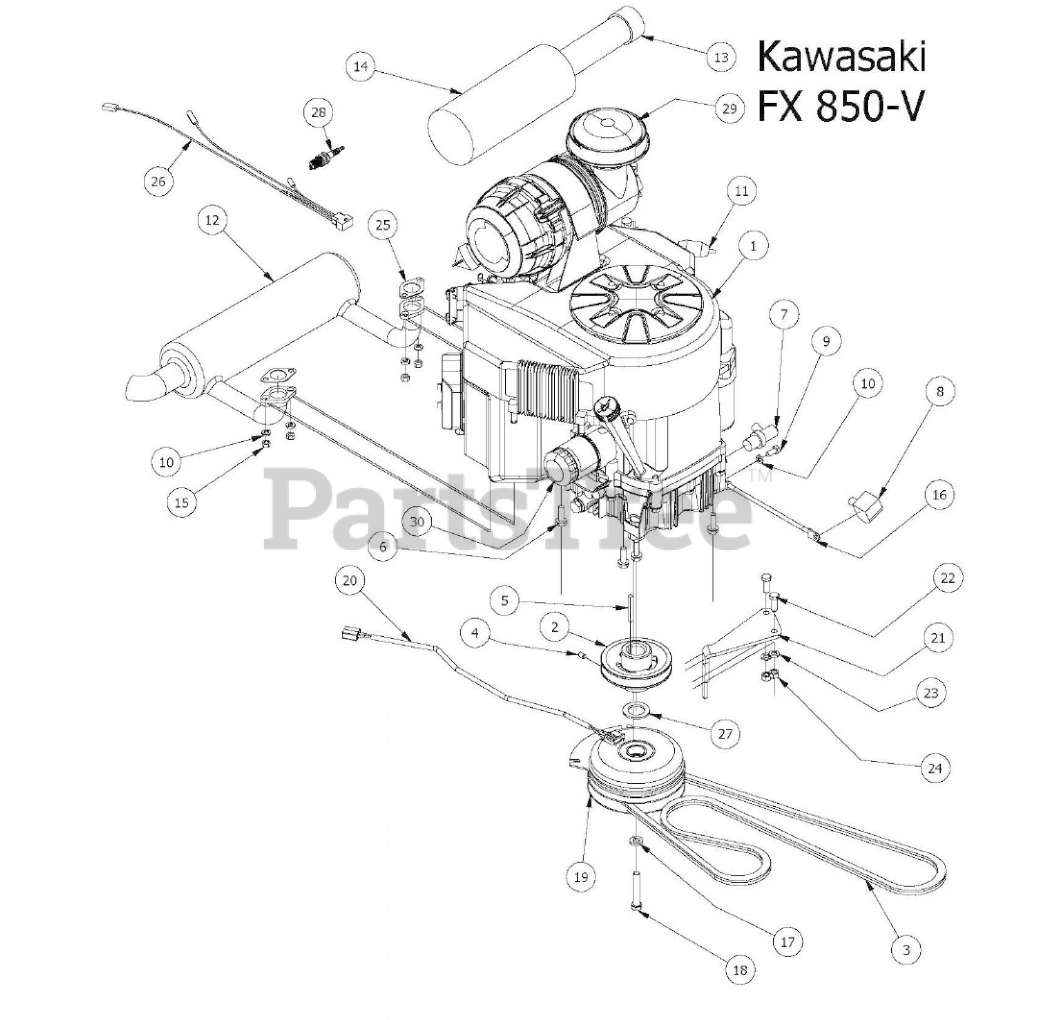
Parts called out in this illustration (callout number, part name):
1	Kawasaki Engine FX-850-V-CS09R
2	4 3/4 Motor Pulley
4	3/8" Set Screw
5	1/4 x 2 Square key Stock
6	3/8 x 1 1/8 bolt
8	Black Boot For Ground Cable
9	M8x1.20X20MM Hex head bolt
10	5/16" Lock Washer
11	Universal Inline Fuel Filter
12	Kawasaki Exhaust
13	Canister Air Filter- Inner
14	Canister Air Filter- Outer
15	M8-1.25 Zinc Nut
16	Ground Cable
17	7/16" Lock Washer
18	7/16" x 2 1/2" Hex Bolt
19	Clutch Assembly
20	Clutch Pigtail
21	PTO Engager Holder
22	3/8" x 1" Hex Bolt
23	3/8" Lock Washer
24	3/8" Hex Nut
25	Exhaust Gasket
26	Harness Adaptor
27	1 1/8" Flat Spacer
28	Spark Plug - Kawasaki
29	Kawasaki Rain Cap
30	Kawasaki Oil Filter
